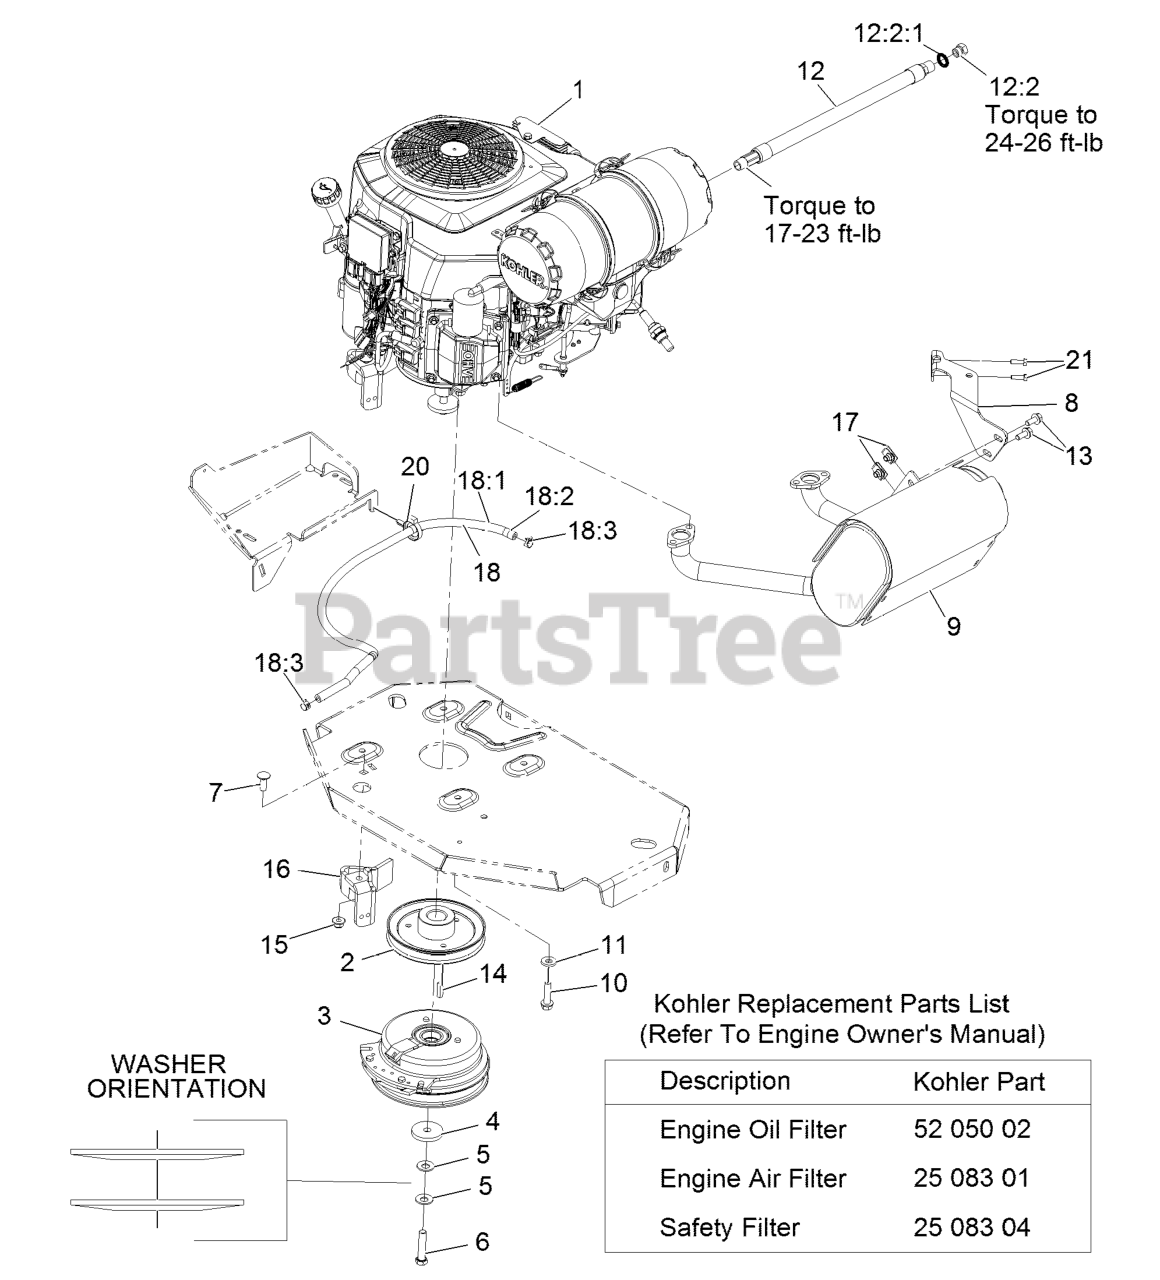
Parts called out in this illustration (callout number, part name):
1	Engine-Kohler
2	SHEAVE
3	CLUTCH KIT
4	WASHER-CLUTCH
5	WASHER-SPRING
6	SCREW-HH W/LOCTITE
7	SCREW-CARR
8	MUFFLER BRACKET KIT
10	SCREW-HWH
11	WASHER-BELLEVILLE
12	OIL DRAIN HOSE ASM
12:2	PLUG-HH
12:2:1	O-RING
13	SCREW-HHF
15	NUT-HF, NI
16	CLUTCH-ANCHOR
18	FUEL LINE ASM
18:1	HOSE-FUEL
18:2	SLEEVE-THERMAL
18:3	CLAMP-HOSE
20	CLAMP-HOSE
21	SCREW-HH M6-1 X 20Mm W/Patch
